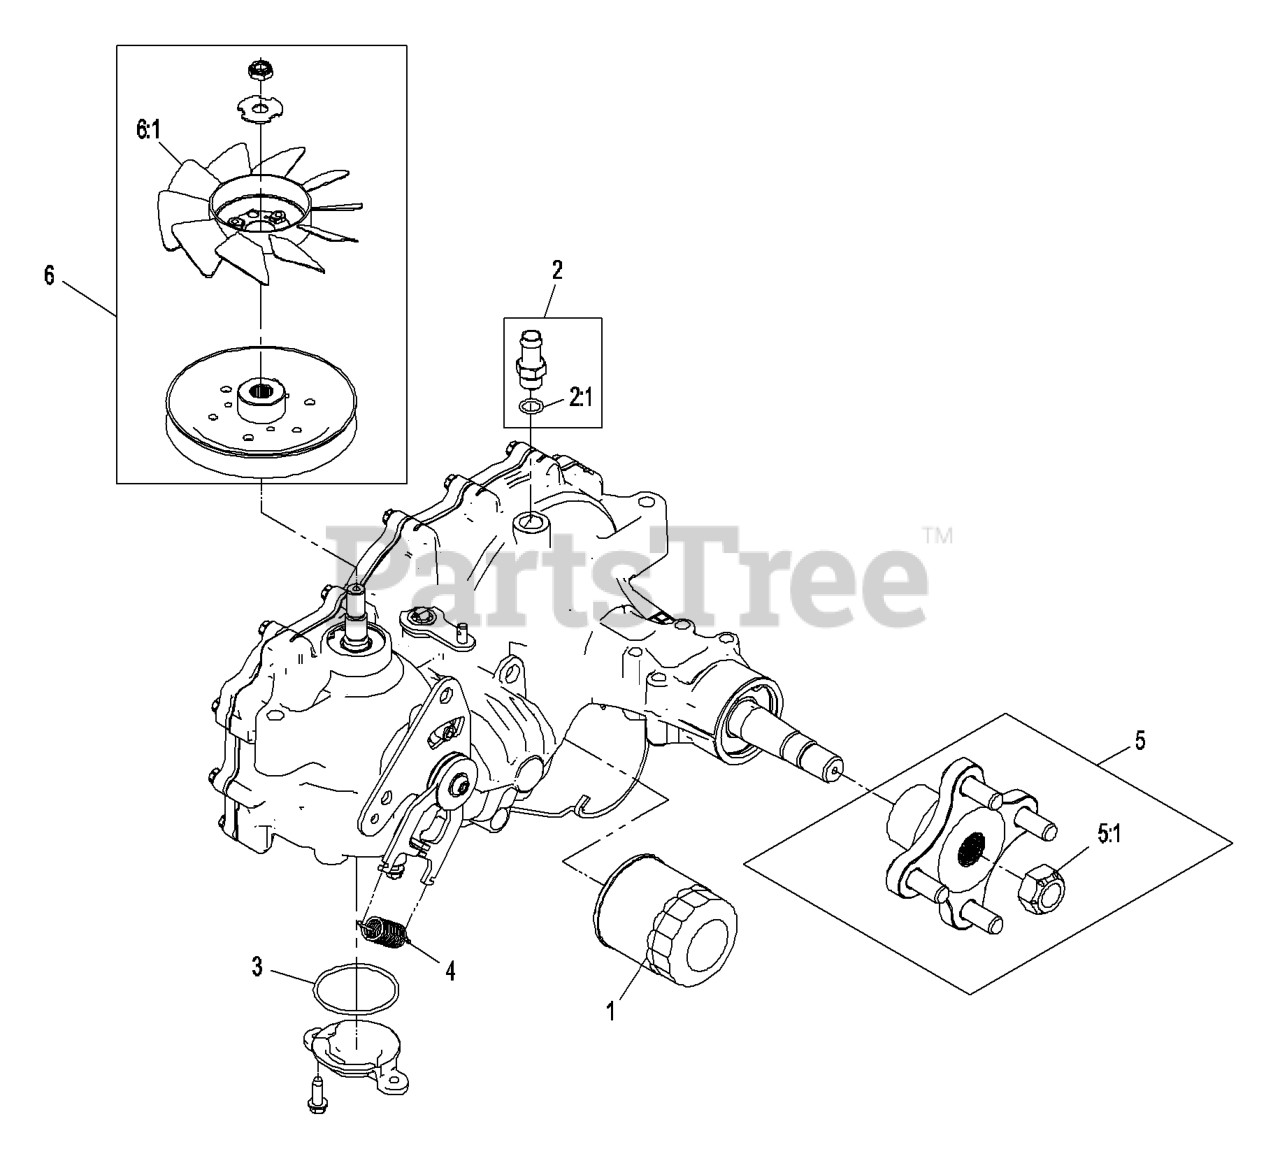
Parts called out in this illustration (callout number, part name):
1	ELEMENT-OIL FILTER, HYD
2	ADAPTER-STRAIGHT
3	O RING-SEAL
4	SPRING-EXTENSION
5	HUB KIT
5:1	NUT-HUB
